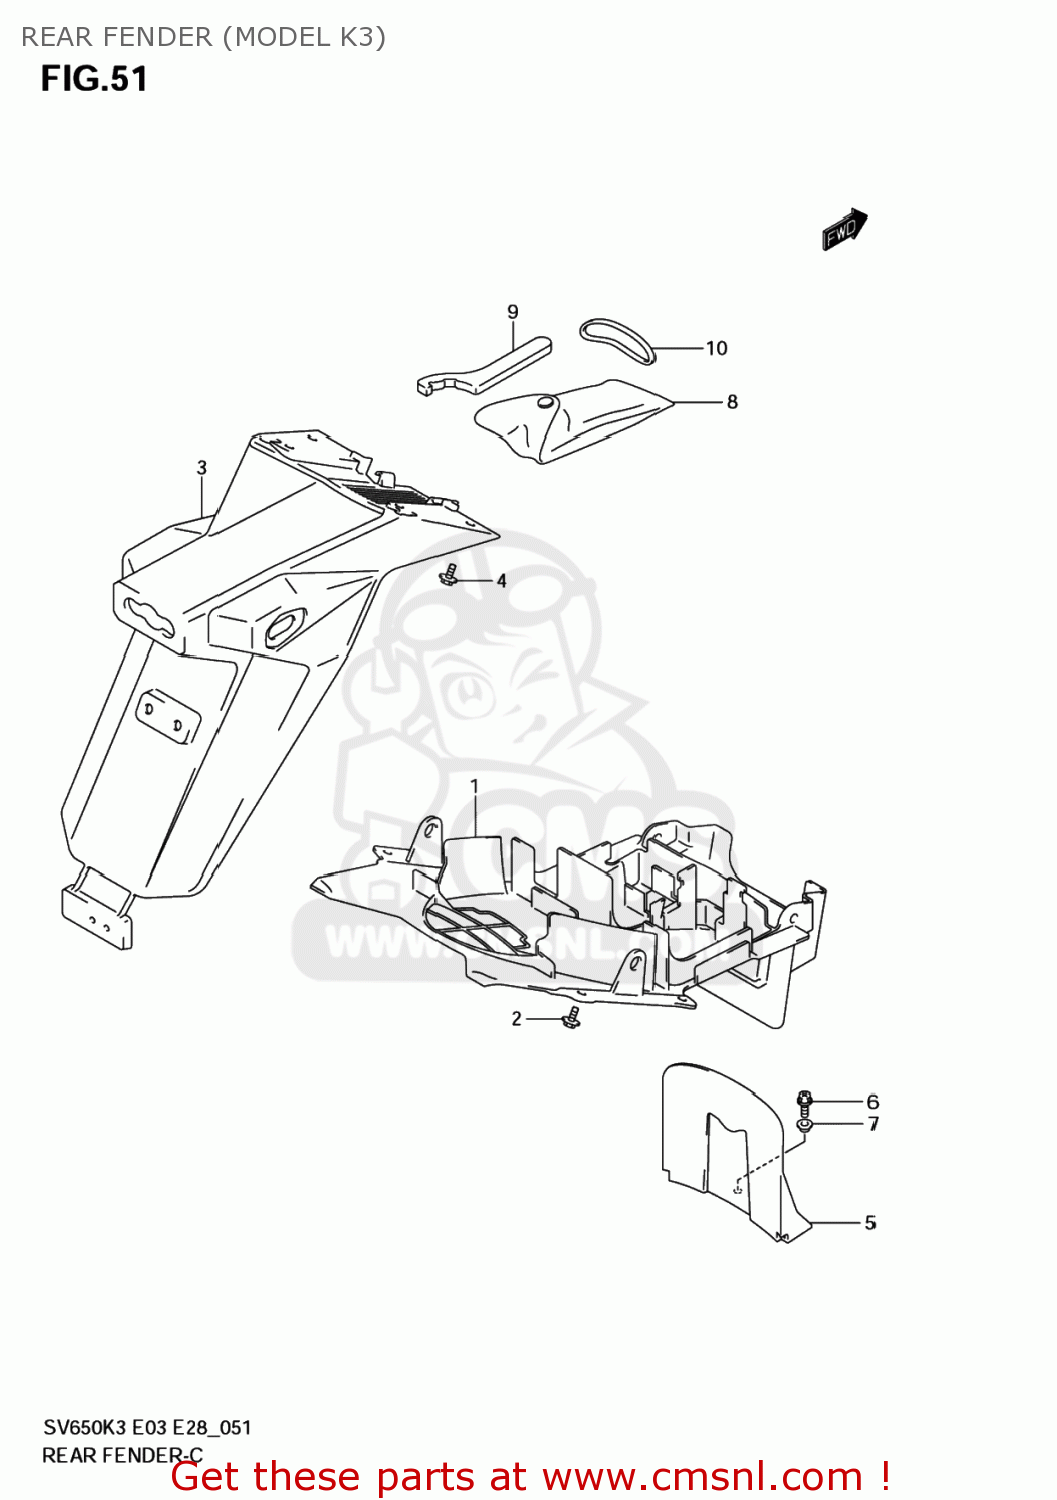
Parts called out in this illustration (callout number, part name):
1	FENDER,RR FR
2	BOLT 6X14
3	FENDER,RR RR
4	BOLT 6X14
5	MUDGUARD,RR FENDER LWR
6	SCREW
7	WASHER
8	TOOL ASSY
9	CLAMP
10	O RING(D:3.5,ID:61)
